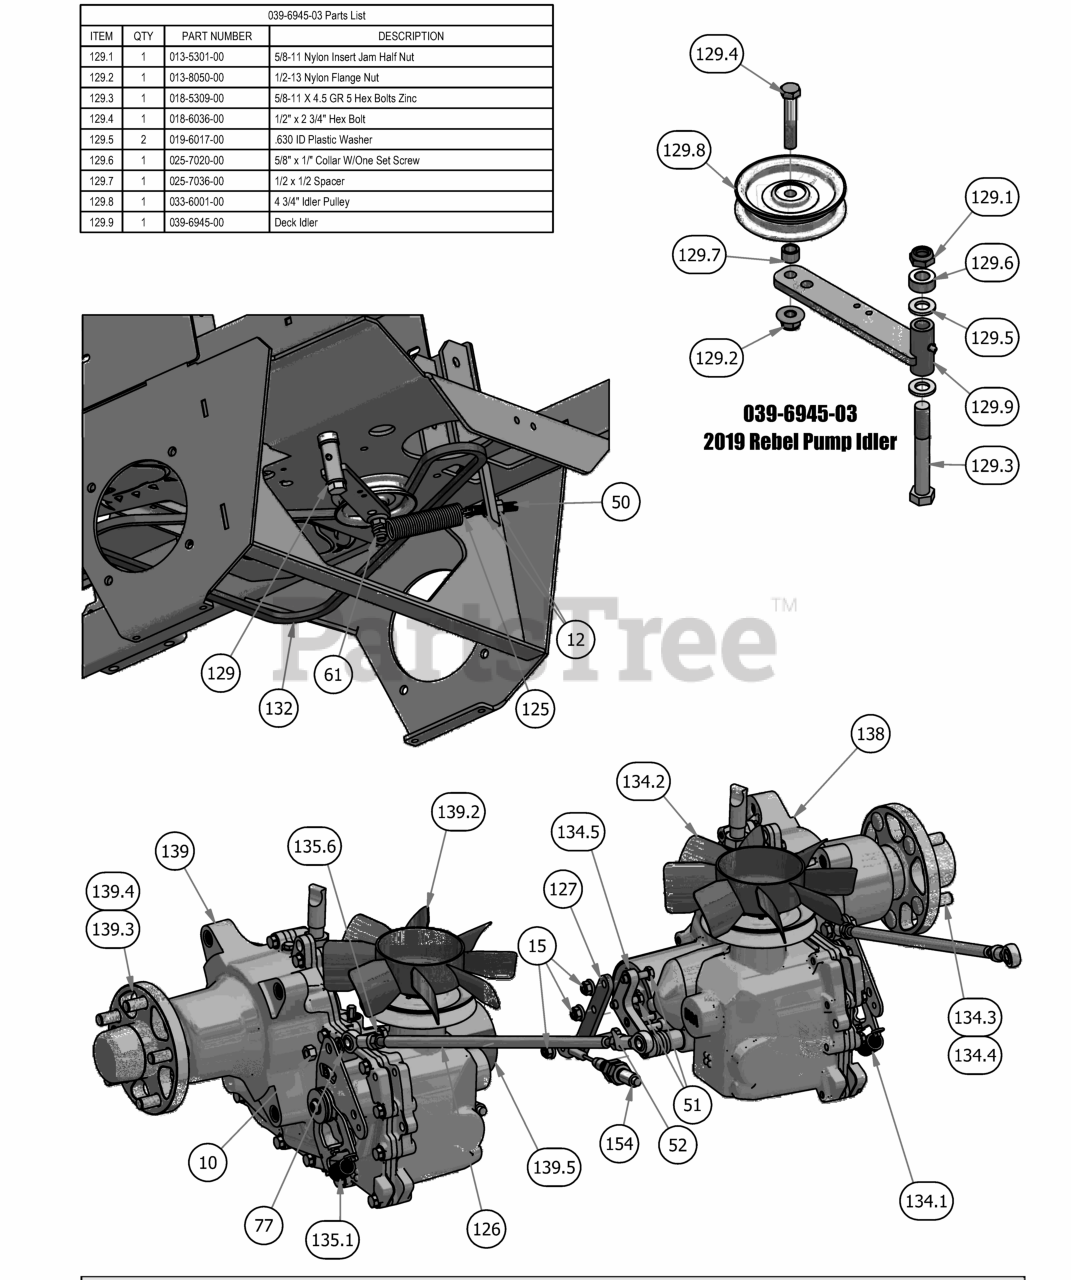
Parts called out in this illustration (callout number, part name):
129.1	5/8-11 Nylon Insert Jam Half Nut
129.2	1/2-13 Nylon Flange Nut
129.3	5/8-11 X 4.5 GR 5 Hex Bolts Zinc
129.4	1/2" x 2 3/4" Hex Bolt
129.5	.630 ID Plastic Washer
129.6	5/8" x 1/" Collar W/One Set Screw
129.7	1/2 x 1/2 Spacer
129.8	4 3/4" Idler Pulley
129.9	Deck Idler
